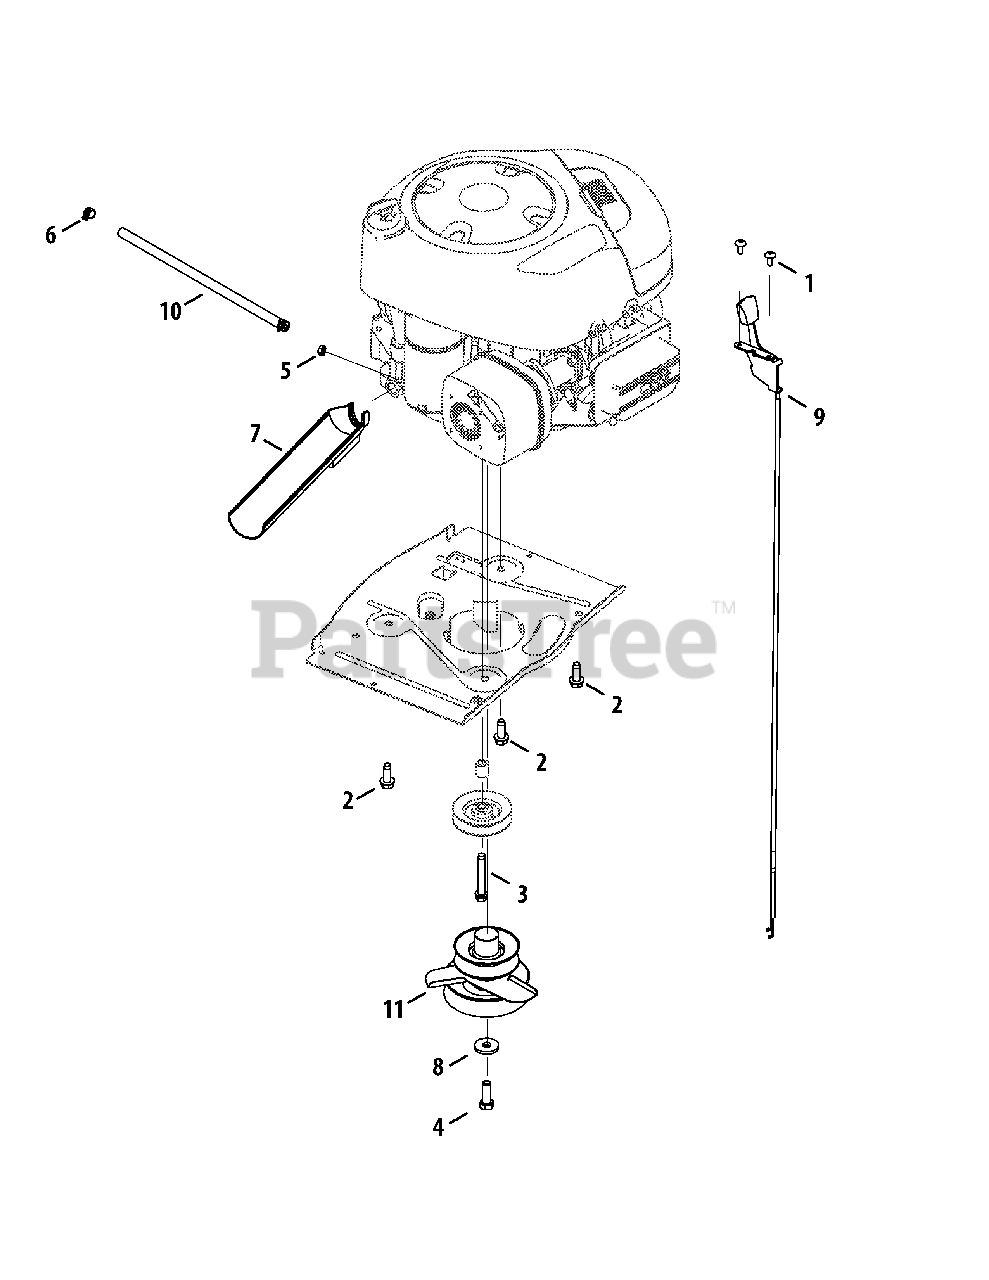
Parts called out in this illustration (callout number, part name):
1	Tap Screw, 1/4-20, 0.500
2	Tap Screw, 3/8-16, 1.000
3	Tap Screw, 3/8-16, 2.250
4	Hex Head Screw, 7/16-20 x 1.25
5	Sems Nut, 1/4-20
6	Hose Clamp, .490 DIA.
7	Oil Drain
8	Flat Washer, .450 x 1.25 x .164
9	Throttle/Choke Cable 31 Lg.
10	Low Permeation Fuel Line, 1/4
11	Engine Pulley, 4.46 / 3.39
